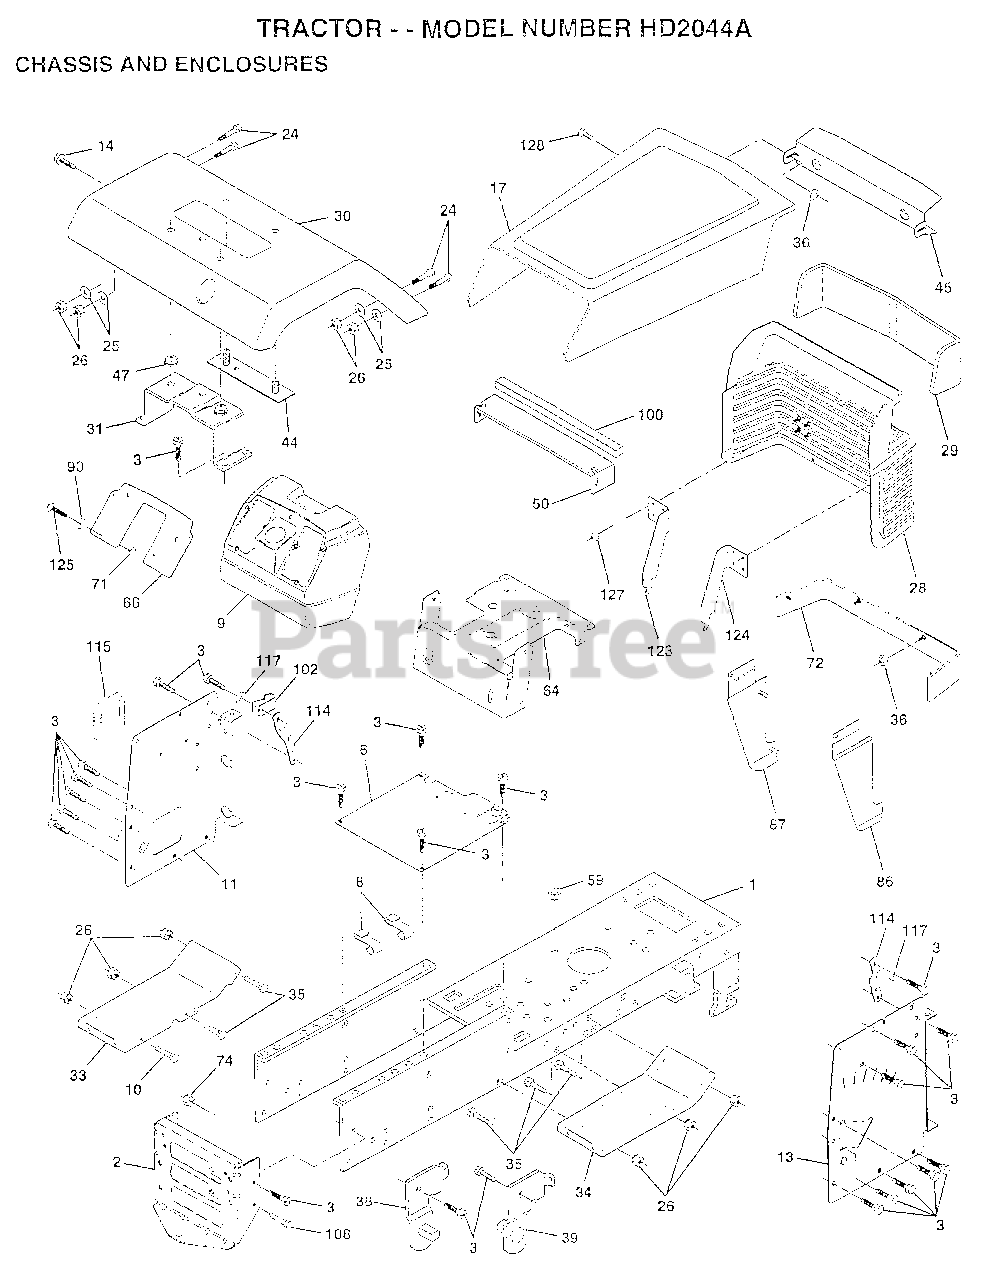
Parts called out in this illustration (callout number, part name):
1	CHASSIS.WLD.11GA
2	DRAW BAR
3	SCREW
9	DASH.PLASTIC.BLK
11	PANEL.DASH.LH.PNT
13	PANEL.DASH.RH.PNT
14	SCREW LT
15	SCREW
17	ASSEMBLY.HOOD.COM
24	BOLT
25	WASHER
26	NUT
28	GRILLE ASM WELD
30	FENDER PNT
31	BRKT.ASM.FENDER
33	FOOTREST.LH.LT/GT
34	FOOTREST.RH.LT/GT
35	BOLT
36	PAL NUT LT
38	BRACKET ASM LH
39	BRACKET ASM RH
44	STRAP ASM FENDER
47	NUT-PUSH YT
65	BOLT
72	STRAP FENDER ASM
86	PANEL.SIDE.ASM.RH
87	ASSY PANEL SIDE LH
90	WASHER PM
102	CLIP T
114	BRACKET.SUPT.DASH
115	COVER ACCESS
117	WASHER.SERRATED.
124	BRACKET.PICK.RH
125	SCREW
127	PAL NUT
128	SCREW SPECIAL
